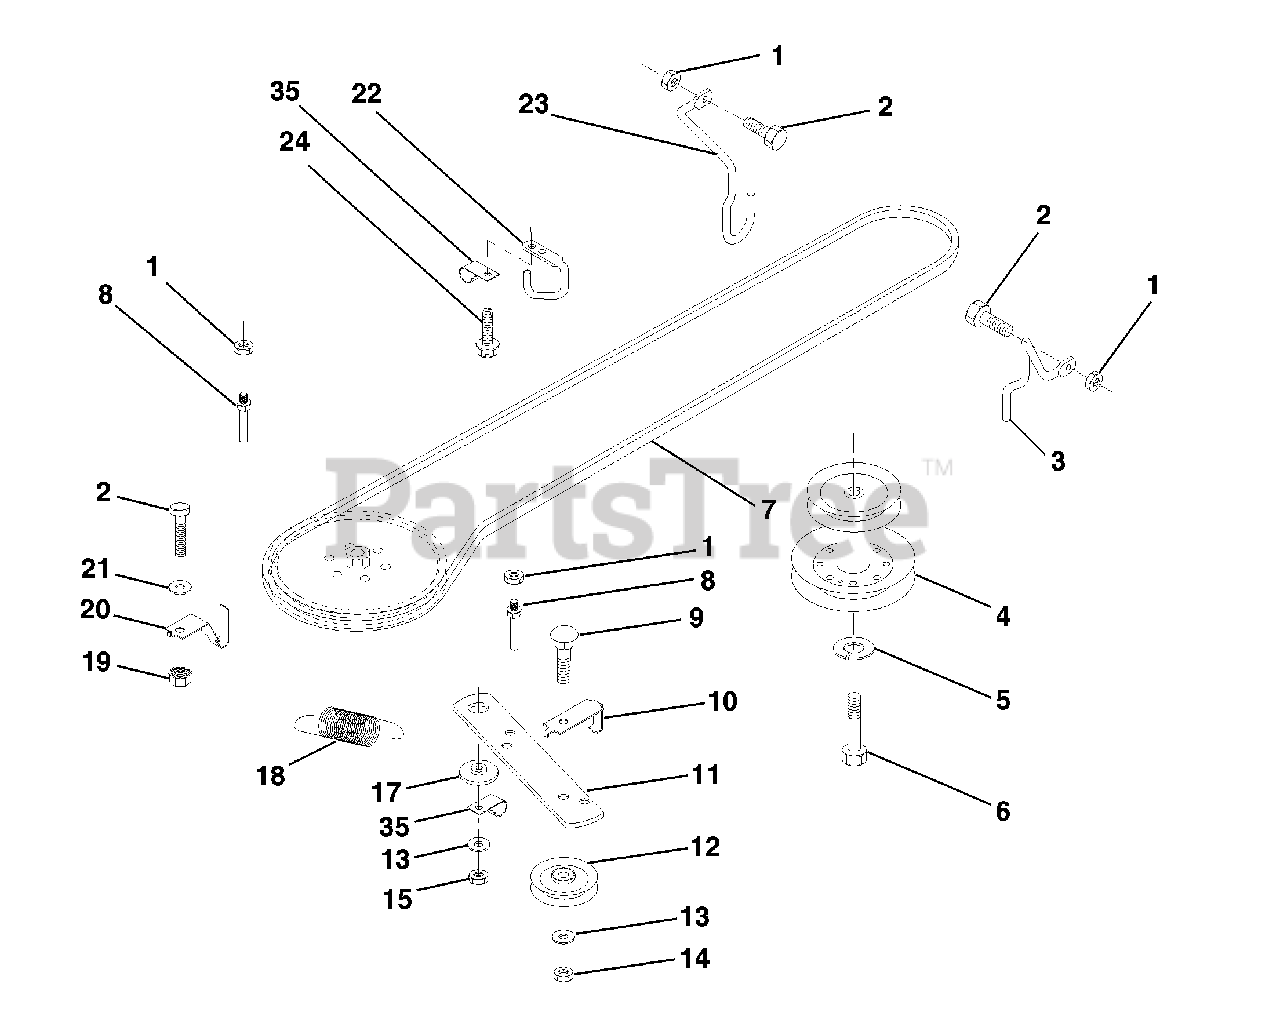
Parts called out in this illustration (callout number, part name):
1	Nut, Crownlock 5/16-18
2	Bolt, Hex Head 5/16-18 UNC x 3/4
3	Keeper, Mower Drive, R.H.
4	Pulley, Engine
5	Washer, Lock 7/16
6	Bolt, Fin Hex M10 x 1.5 x 75 MM
7	Traction, V-Belt Drive
8	Keeper, T/A, Ground Drive Belt
9	Bolt, Carriage 3/8-16 UNC x 1-1/2
10	Keeper, Ground Drive Belt Idler
11	Arm, Ground Drive Clutch
12	Idler, Flat
13	Washer 13/32 x 13/16 x 16 Gauge
14	Nut, Hex, Centerlock 3/8-16 UNC
15	Nut, Crownlock 3/8-16 UNC
17	Spacer, Retainer
18	Spring, Extension
19	Nut, Hex, Keps 5/16-18 UNC
20	Keeper, T/A, Ground Drive Belt
21	Washer 11/32 x 5/8 x 16 Gauge
22	Keeper, Frame Ground Drive Belt
23	Keeper, Belt LH Front
24	Screw, Thd. Cut 1/4-20 x 1/2
35	Clip, Insulated
